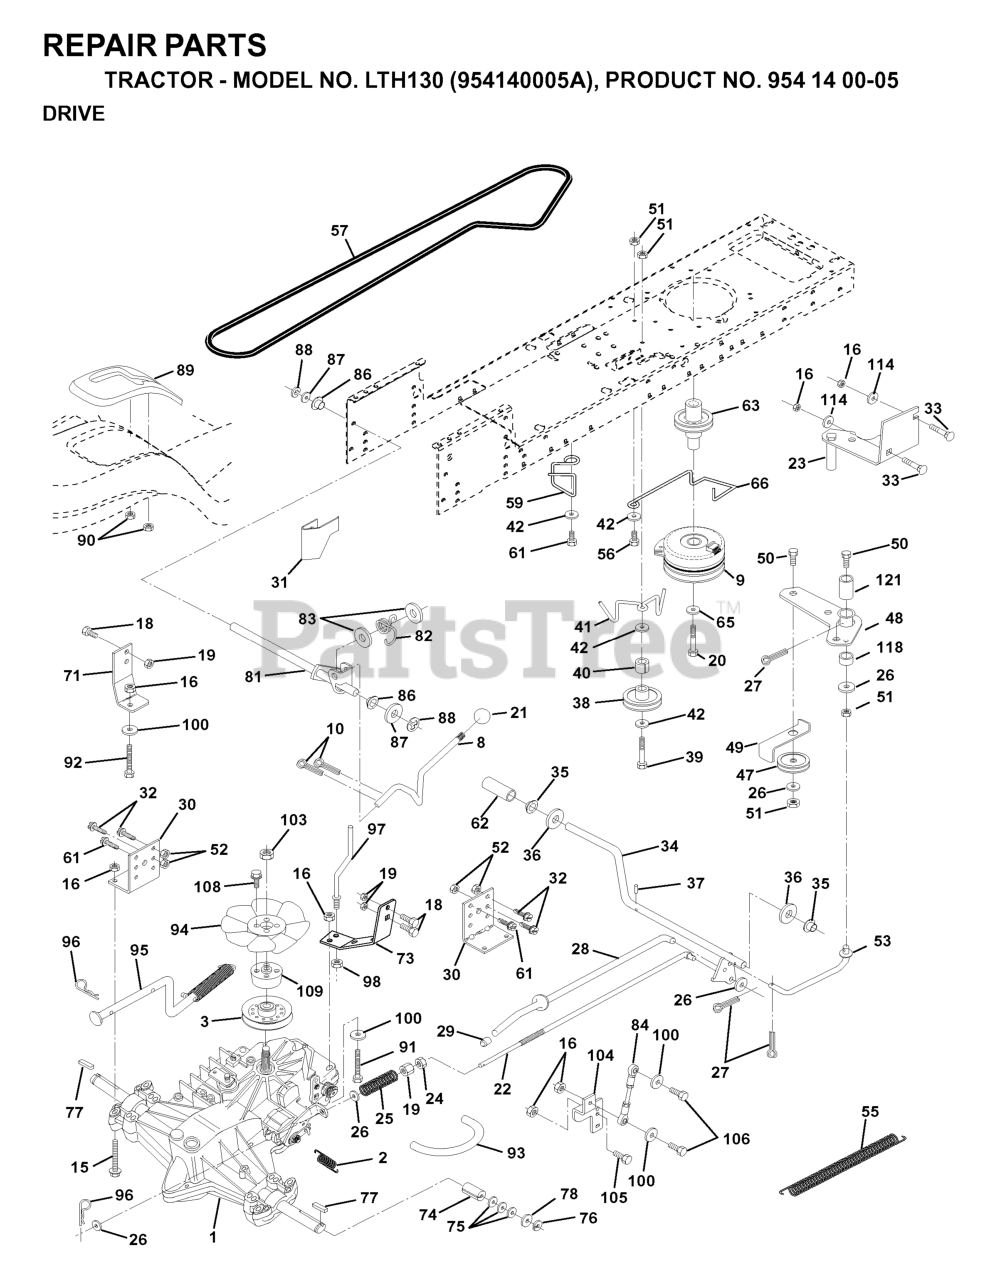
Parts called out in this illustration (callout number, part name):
1	TRANSAXLE.HYDRO.319-0500.LR
2	SPRING BRAKE
3	PULLEY.4.20.HYDRO
8	ROD SHIFT FENDER
9	CLUTCH.ELECT.EVX.
10	PIN COTTER
15	BOLT HEX 5/16-18 GR 5
16	NUT.71038.31-18.HEX.NYLOCK
18	BOLT
19	NUT
20	BOLT HEX
21	KNOB.DUCKHEAD.1/2
22	ROD BRAKE HYDRO
23	BRACKET, ASM CLUTCH MTG
24	NUT
25	SPRING ROD LT
26	WASHER
27	COTTER PIN
28	ROD BRAKE PARK LT
29	PLUNGER CAP
30	BRACKET TRANSAXLE
31	KEEPER BELT LH
32	BOLT
33	RP BOLT 5/16-18 X3/4 ZN/YEL GR
34	SHAFT, FOOT PEDAL
35	BEARING.NYLON
36	WASHER LT
37	DRIVE PIN
38	PULLEY.IDLER.FLAT
41	KEEPER, BELT IDLER
42	WASHER
47	IDLER PULLEY
48	BELLCRANK ASSEMBLY
49	RETAIN BELT
50	BOLT
52	LOCKNUT
53	LINK, CLUTCH LT
55	SPRING, RETURN LT
59	KEEPER CENTER SPAN
61	SCREW
62	PEDAL COVER T
63	PULLEY, CLUTCH ELECT EVX
65	LOCKWASHER
66	KEEPER BELT ENGINE
71	STRAP TORQUE LH HYDRO
73	STRAP TORQUE RH HYDRO
74	SPACER SPLIT
77	SQUARE KEY
81	SHAFT ASM CROSS HYDRO
82	SPRING,TORSION
83	WASHER
84	ROD, TIE HYDRO
86	BUSHING.STEERING.ROD LTB-WSL
89	CONSOLE SHIFT
90	NUT.PUSH.3/16
91	BOLT.FIN HEX 5/16-18UNC X2 1/4
92	HEX BOLT
93	LINE FUEL HYD 4"
94	FAN 7" HYDRO
95	CONTROL ARM, BYPASS HYDRO
96	RETAINER M
97	KEEPER BELT RH
100	WASHER M
103	NUT.HEX.1/2-20
104	ARM, CONTROL HYDRO
106	BOLT.5/16-18X1-1/4 FULL.THREAD
109	ADAPTOR FAN HYDRO
114	Washer 11/32 x 3/4 x 14 Gauge
118	SPACER BELLCRANK
121	NYLINER CLUTCHING
